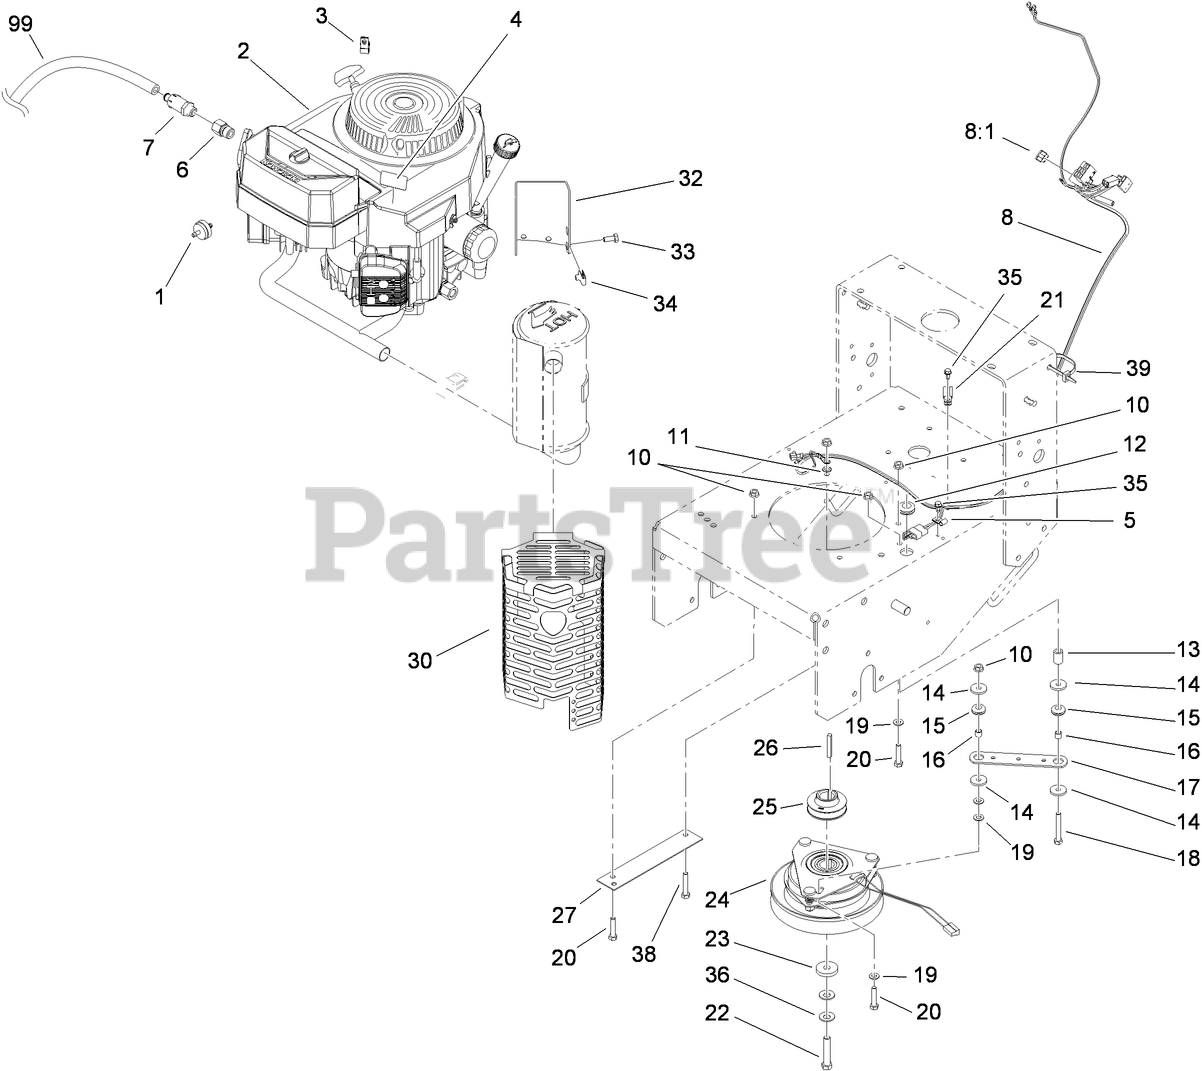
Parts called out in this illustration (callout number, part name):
1	FILTER-FUEL
3	CLAMP-CABLE
4	DECAL-WARNING
5	CLIP-CLOSED, INSULATED
6	Adapter
7	VALVE-DRAIN, OIL
8	HARNESS-WIRE
8:1	FUSE-BLADE, 7.5 AMP
10	NUT-HF
11	WASHER-LOCK
12	GROMMET
13	TUBE-RETAINER
14	WASHER
15	GROMMET
16	SPACER
17	STRAP-CLUTCH, BRAKE
18	SCREW-HH
19	WASHER-PLAIN
20	SCREW-HH
21	CLAMP-R
22	SCREW-HH
23	WASHER
24	CLUTCH / BRAKE ASM
25	PULLEY-DRIVE
26	KEY-SQUARE
27	COVER-PULLEY
30	MUFFLER SHIELD ASM
32	BRACKET-MUFFLER
33	SCREW-HH
34	NUT-U
35	SCREW
36	WASHER-SPRING
38	SCREW-HH
39	TIE-CABLE
99	HOSE-DRAIN, OIL
